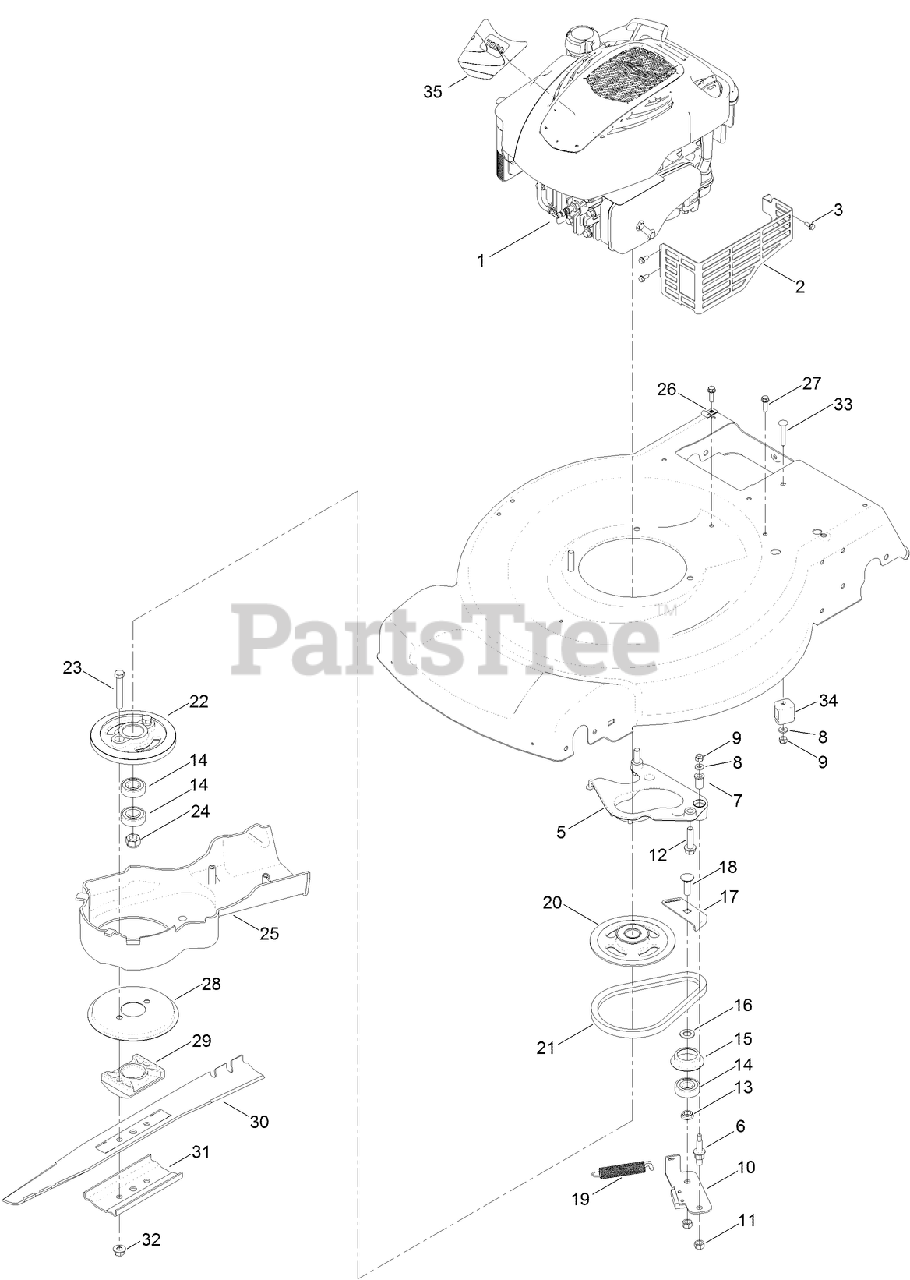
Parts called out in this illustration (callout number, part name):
2	SHIELD-MUFFLER
3	SCREW-TAPTITE
5	PLATE-ANCHOR
6	BOLT-SHOULDER
7	BUSHING
8	WASHER-FLAT
9	NUT-LOCK, NI
10	PLATE-BRAKE
11	NUT-HEX
12	SCREW-HWH
13	SPACER-BEARING
14	BEARING-BALL
15	RETAINER-BELT
16	WASHER-PLAIN
17	PLATE-GUIDE
18	BOLT-CARR
19	SPRING-TENSION, BRAKE
20	PULLEY
21	BELT
22	DRUM
23	SCREW-HH
24	NUT-HEX
26	CLIP-CLOSED, INSULATED
27	SCREW-HWH
28	DISC
29	SUPPORT-BLADE
30	BLADE
31	SUPPORT-BLADE
32	NUT-FLANGE, LOCK
33	SCREW-CARR
34	ANCHOR-CABLE
35	DECAL-SHROUD
